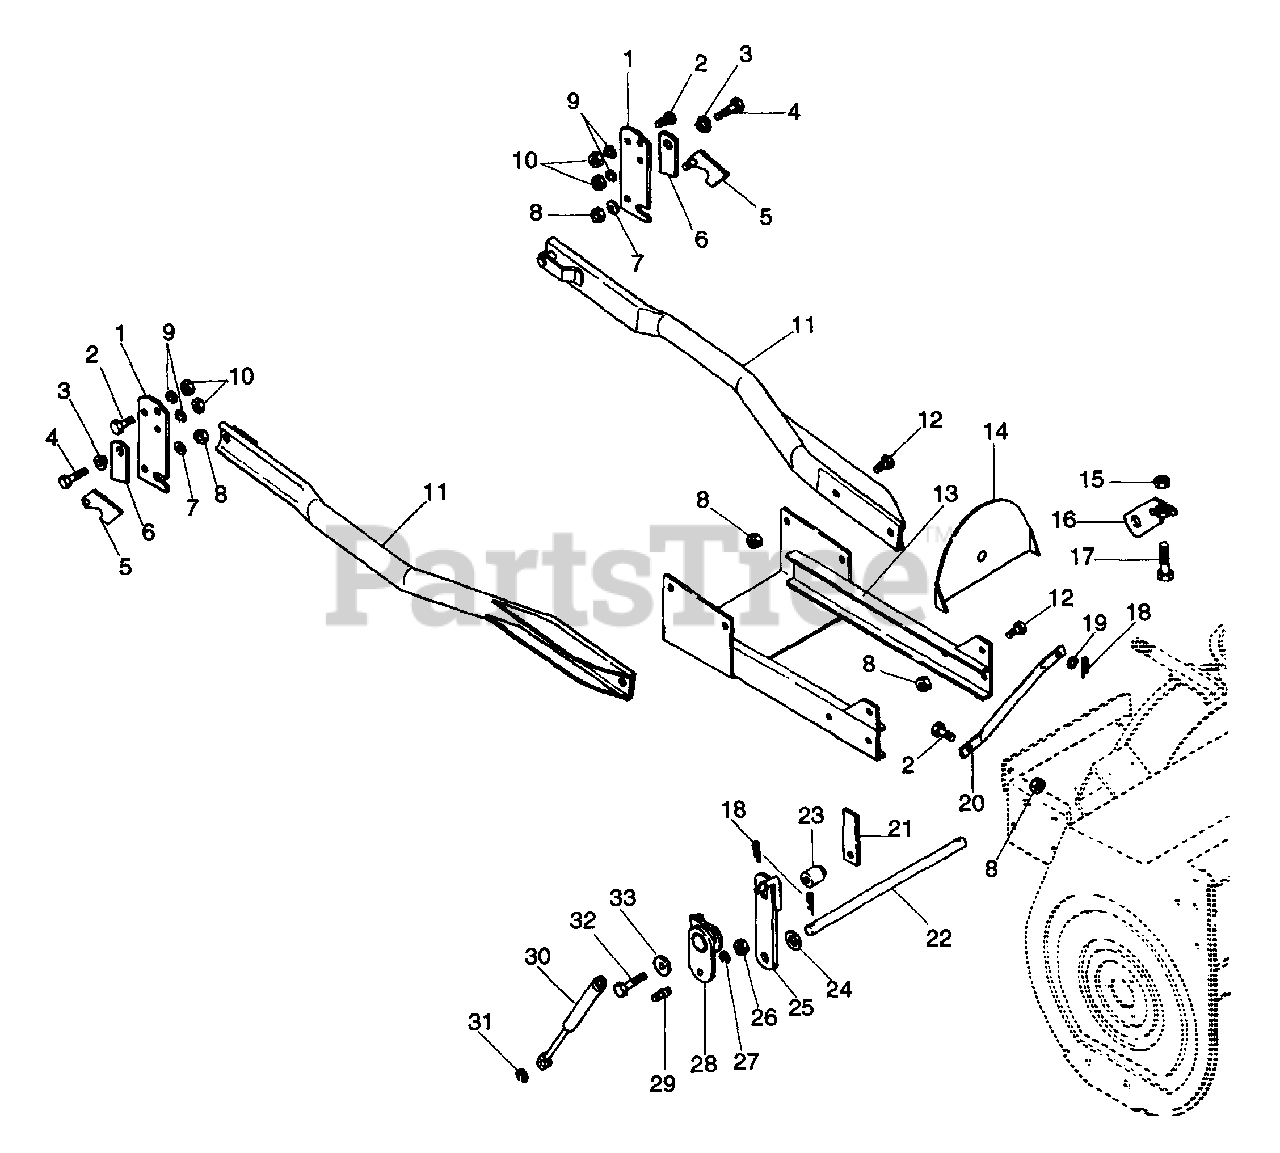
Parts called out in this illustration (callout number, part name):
1	REAR HANGER
2	BLT-HEX .38-16X1.00 PL GR5
3	SPACER .400X.625X.400X.875
4	BLT-HEX .38-16X1.50 PL GR5
5	LATCH RH
6	LOCK STOP
7	SPRING WASHER
8	NUT-LK TOP .375-16 GR C YWZC
9	WSHR-LK .375X.115 HVY PL
10	NUT-HEX .375-16
11	REAR ATTACHMENT BRACE
12	BLT-HEX .38-16X.75 PL GR5
13	CHANNEL-CROSS
15	NUT .50-13 PL
16	ADJUST LINK
17	BLT-HEX .50-13X2.00 PL GR2 FTH
18	PIN-HAIR INT .09X.188 PL
19	WSHR-FL-STL .390X.750X.125 PL
21	BOLT PLATE
22	PIVOT ROD
24	WSHR-FL-STL.656X1.312X.095 PL
25	RH LIFT
26	NUT-JAM .312-18 PL
27	WSHR-LK .313X.078 PL MED
28	SPRING BRACKET RH
29	PIN,THREADED
30	SG- GAS COMP .31X.75X10.00
31	RG-RTNG-EXT .312 X .020
32	BLT-HEX .38-16X2.00 PL GR2
33	WSHR-FL-STL .406X1.125X.125 PL
